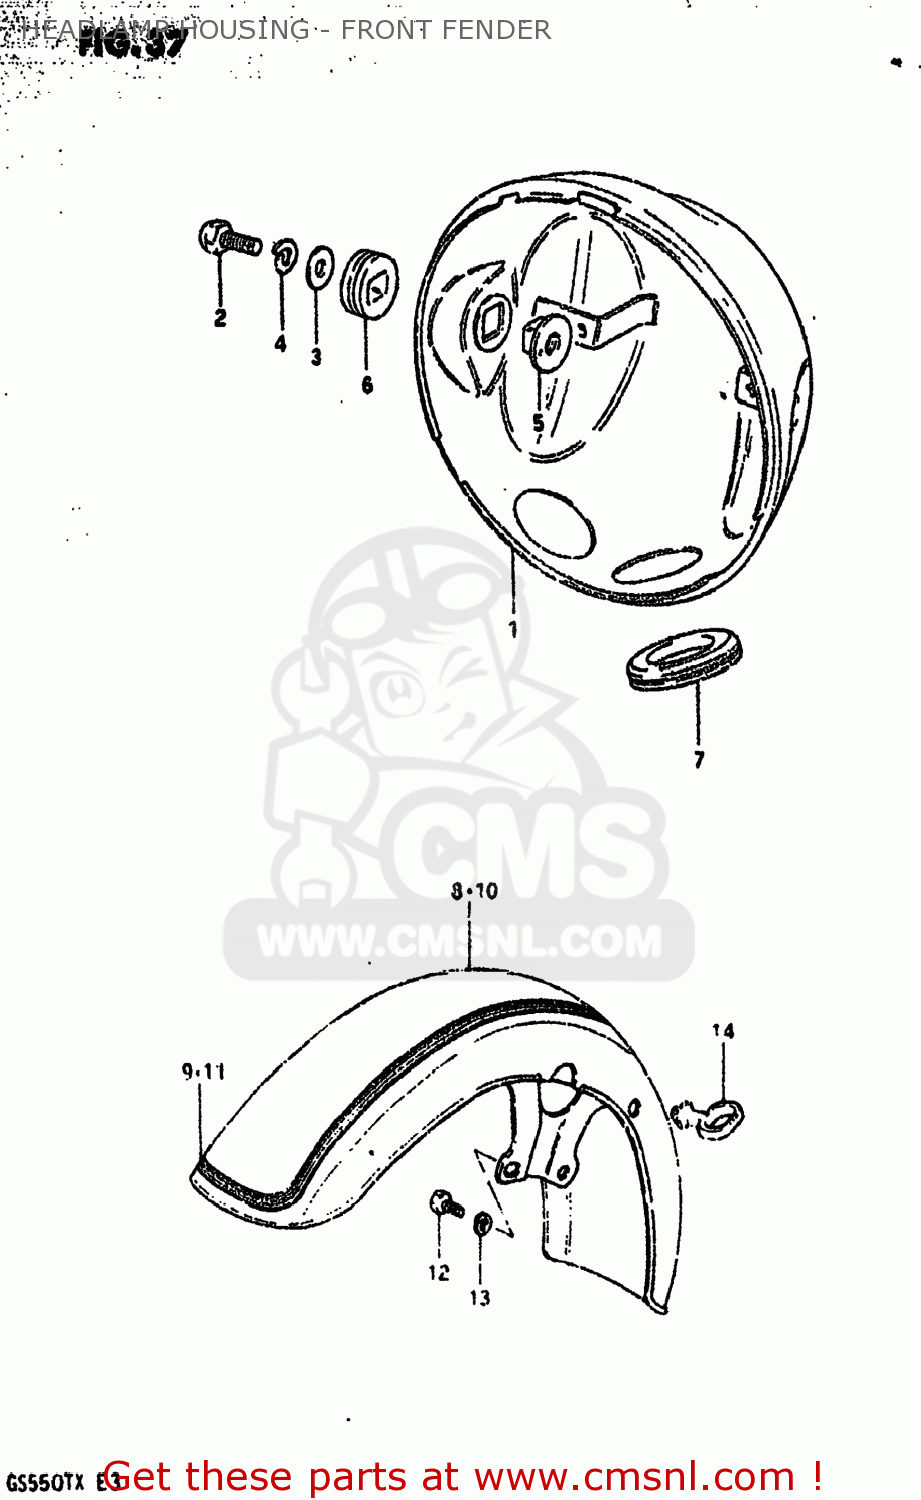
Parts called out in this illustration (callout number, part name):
1	HOUSING,HEADLAMP
2	BOLT
3	WASHER
4	LOCK WASHER
5	SPACER,HEADLAMP HOUSING
6	CUSHION,HEADLAMP HOUSING
7	GROMMET,HEADLAMP HOUSING
8	FENDER,FRONT
9	TAPE,FRONT FENDER
10	FENDER,FRONT
11	TAPE,FRONT FENDER
12	BOLT
13	LOCK WASHER
14	GUIDE,CABLE
